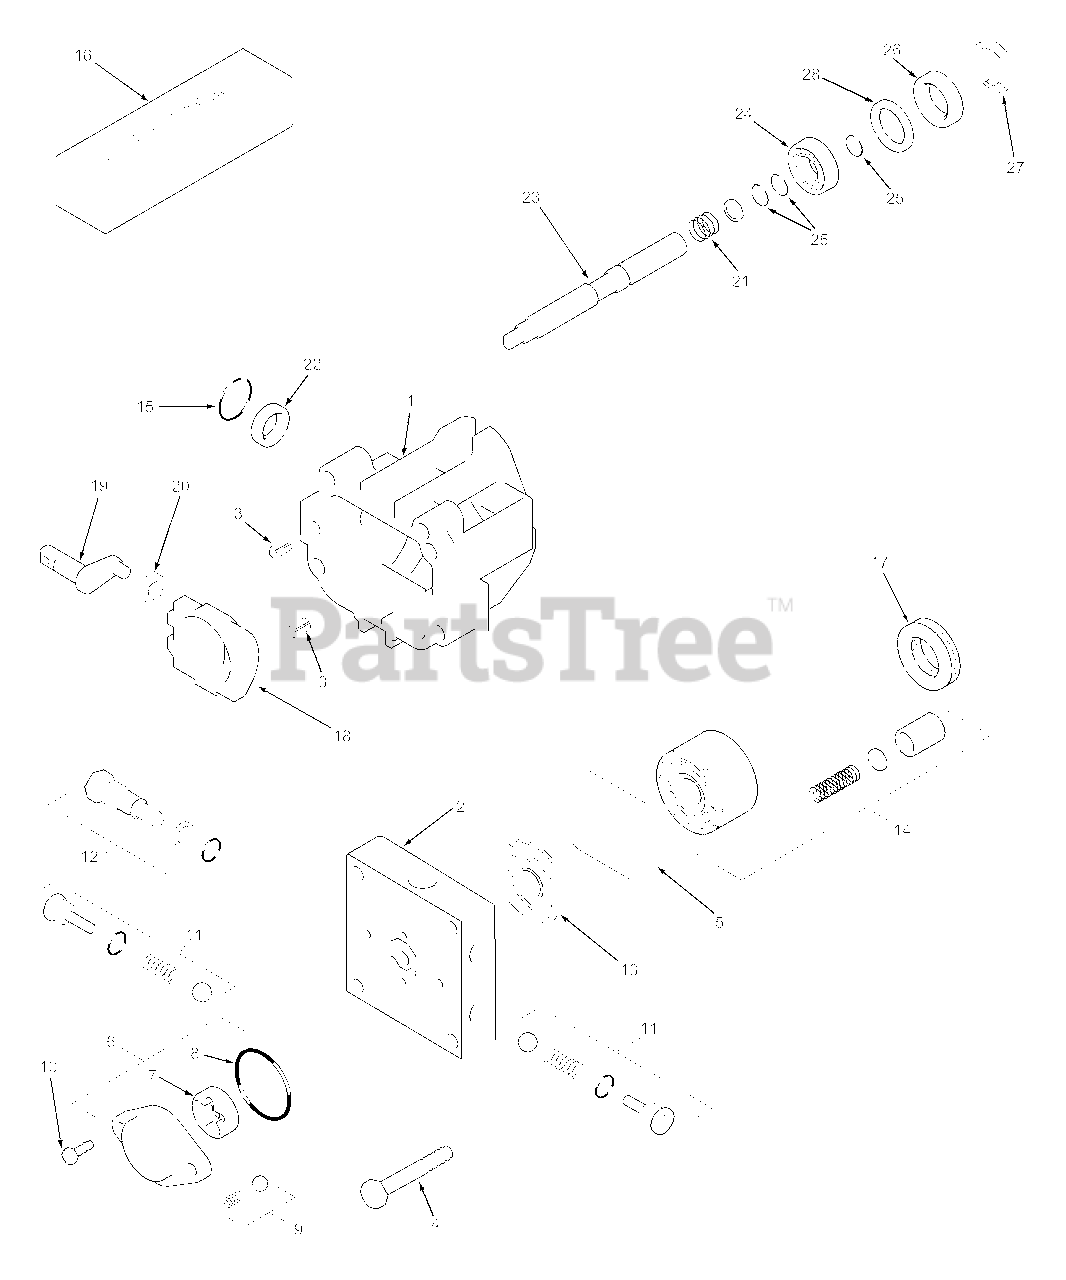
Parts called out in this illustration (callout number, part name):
1	Housing Kit
2	End Cap
3	Straight Headless Pin
4	Socket Head Screw
5	End Cap Gasket
6	Charge Pump Kit
7	Gerotor Assembly
9	Charge Relief Valve Kit
10	Socket Head Screw
11	Check Valve Kit
12	Bypass Valve Kit
13	Valve Plate
14	Cylinder Block Kit
15	Trunion Seal Retaining Ring
16	Overhaul Kit
17	Roller Thrust Bearing
18	Swash Plate
19	Trunnion Arm
20	Guide Slot
21	Block Spring
22	Lip Seal
23	Pump Shaft
24	Ball Bearing
25	Retaining Ring
26	Lip Seal
27	Retaining Ring
